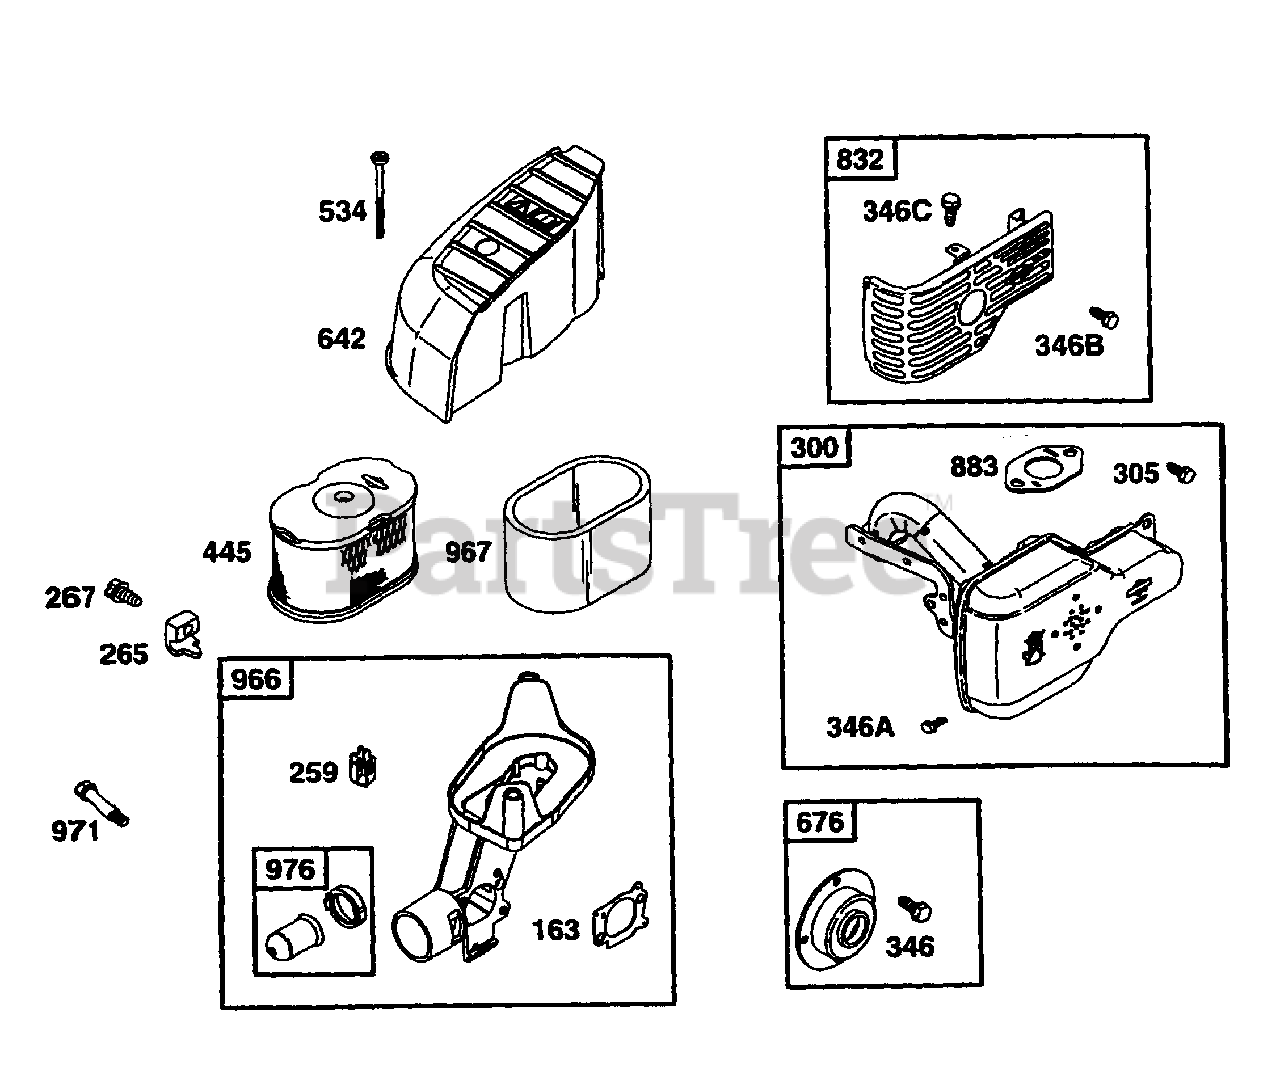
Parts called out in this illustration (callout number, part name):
163	Air Cleaner Gasket
259	Casing Clamp Bracket
265	Casing Clamp
267	Slotted Hex Screw
305	Hex Screw
346	Hex Screw
346A	Hex Screw
346B	Hex Screw
346C	Hex Screw
445	Air Filter
534	Shoulder Screw
642	Air Cleaner Cover
676	Muffler Deflector
832	Muffler Guard
883	Exhaust Gasket
966	Air Cleaner Base
967	Pre Filter
971	Shoulder Screw
976	Carb Primer
